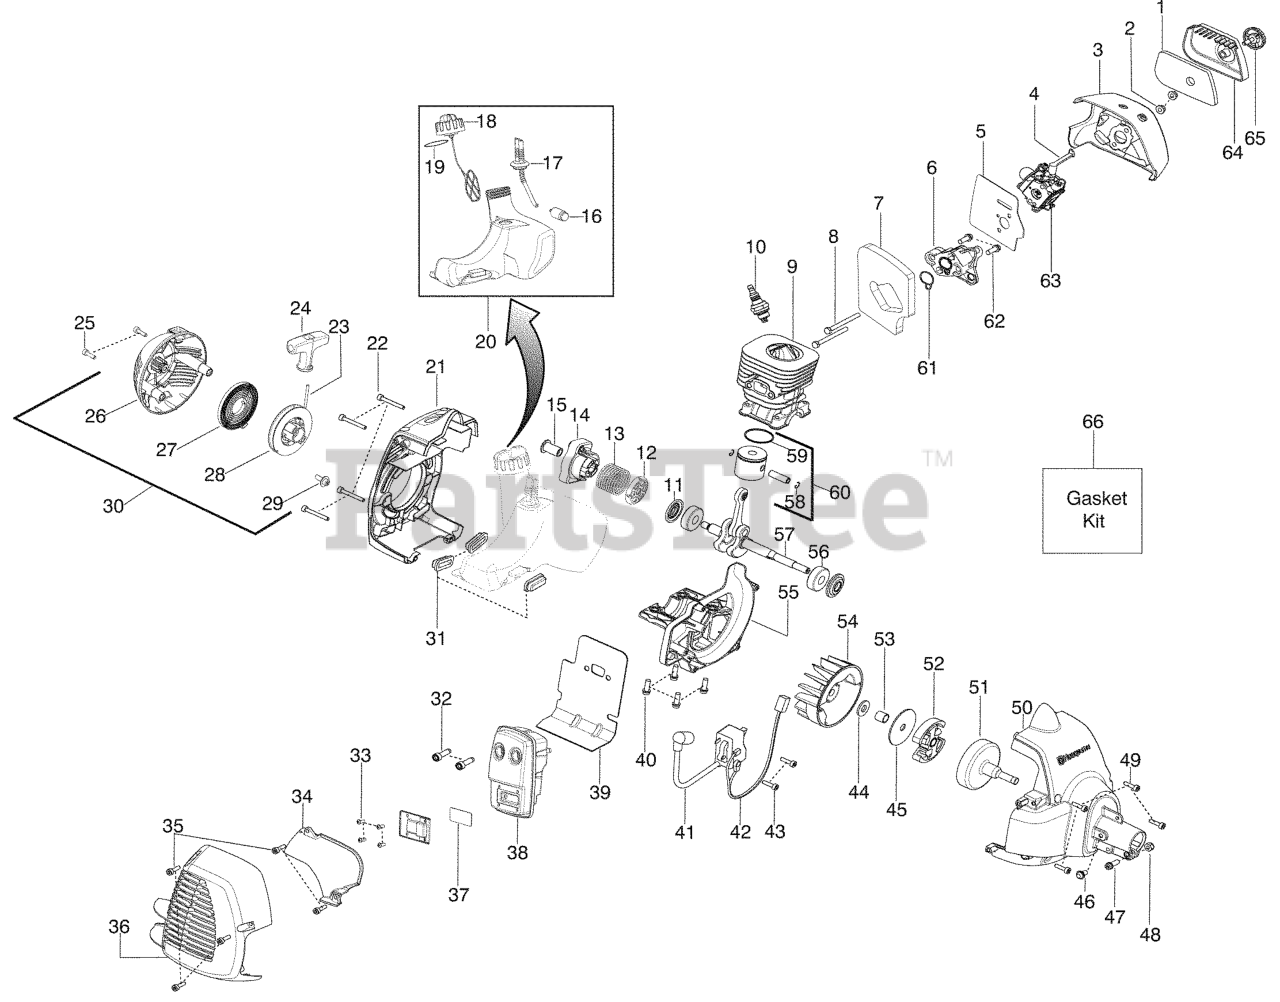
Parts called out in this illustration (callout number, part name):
1	FILTER AIRBOX
3	Air Box
4	CHOKE LEVER
5	KIT GASKET CARB
6	CARB ADAPTOR
7	KIT GASKET 28CC
8	BOLT CARB ADAPTOR
9	CYLINDER
10	Plug-Spark (RCJ-8Y)
11	KIT SEAL CRANKSHAFT
12	WASHER STARTER
13	SPRING STARTER CUP
14	ASSY STARTER CUP
15	COUPLING STARTER
16	FUEL PICK-UP ASSY
17	KIT FUEL LINE
18	ASSY-CAP W/RETAINER
19	KIT GASKET 28CC
20	FUEL TANK ASSY
21	REAR SHROUD
24	STARTER HANDLE GRAY
25	SCREW M5-0.8X30MM
26	STARTER HOUSING
27	%KIT STARTER SPRING
28	KIT STARTER PULLEY
30	ASSY-STARTER HSG.
31	ISOLATOR FUEL TANK
32	BOLT MUFFLER
33	SCREW-10-16 X 1/2 HI-LO
34	SHIELD HEAT
35	SCREW M4 X 1.75 PT 16MM
36	GUARD-MUFFLER
37	KIT SPARK ARRESTOR SCREEN
38	ASSY-MUFFLER
39	KIT GASKET 28CC
40	SCREW-M5-0.8 X 25MM(TAP)
41	IGNITION MODULE MBU-7
42	ASSY MODULE LEAD WIRE
43	SCREW M4 X .70 TT 16MM
44	WASHER CLUTCH
45	WASHER-CLUTCH
48	LOCKNUT-HEX 10-24
49	SCREW M4 X .70 TT 16MM
50	FAN HSG ASSY
51	Assy-Clutch Drum
52	%KIT CLUTCH ASSY
53	SPACER FLYWHEEL
55	CRANKCASE CASTING
56	BEARING RADIAL BALL (6201)
57	KIT CRANKSHAFT ASSY
58	WRIST PIN RET.
59	RING PISTON
60	KIT PISTON 28CC TRIMMER
61	KIT GASKET 28CC
62	SCREW-M5-0.8 X 25MM(TAP)
63	Kit-Carb.
64	COVER-AIR BOX
65	KNOB ASSY AIRBOX COVER
66	KIT GASKET 28CC
